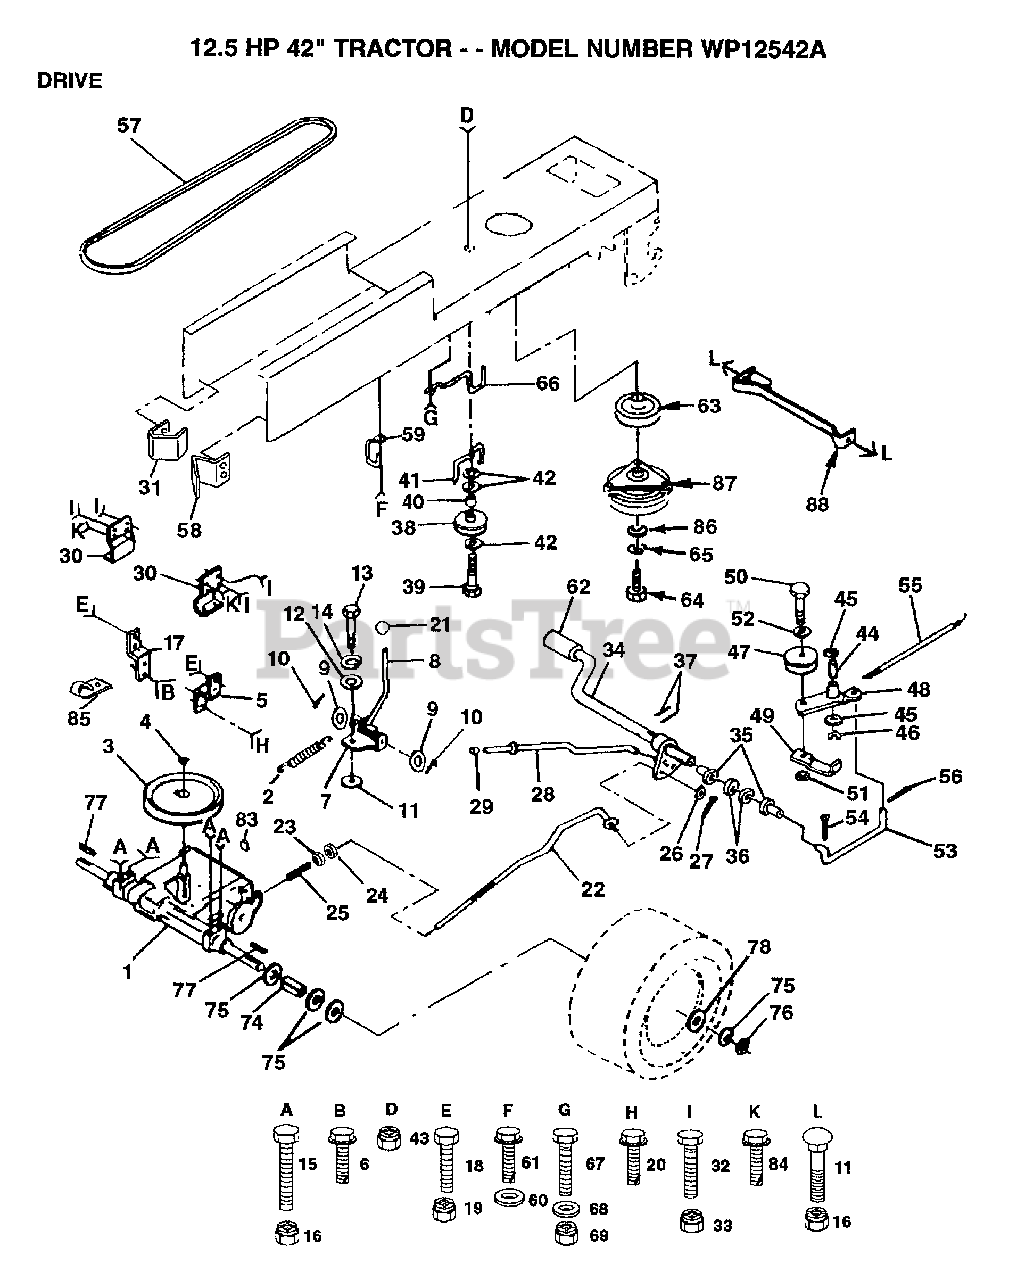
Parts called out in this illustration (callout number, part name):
3	PULLEY TRANS
5	STRAP TORQUE
6	SCREW
8	SHIFT ROD
9	WASHER
10	PIN COTTER 1/8
11	WASH-SHFT PLT LT
12	WASHER LT
14	LOCKWASHER
15	BOLT
17	STRAP TORQUE
20	SCREW
21	KNOB T (1/2-HOLE)
22	BRAKE ROD
23	NUT
24	NUT
25	SPRING ROD LT
26	WASHER
27	COTTER PIN
28	BRAKE PARK ROD
29	PLUNGER CAP T
30	TRANSAXLE MTG BKT
31	"KEEPER,BELT LH T"
32	BOLT
35	NYLON BEARING
36	WASHER LT
38	PULLEY.IDLER.FLAT
39	BOLT
40	SPACER T
41	BELT KEEPER LT
42	WASHER
44	"LY, BEARING"
45	WASHER LT
46	KLIP RING
48	ARM IDLER
49	RETAIN BELT
52	WASHER
53	"LINK, CLUTCH T"
54	COTTER PIN
55	"SPRING, RETURN LT"
56	COTTER PIN
58	"KEEPER,BELT RH T"
60	WASHER
61	SCREW
62	PEDAL COVER T
65	LOCKWASHER
66	KEEPER.BELT.ENG.L
67	BOLT
68	WASHER
74	SPACER LT
75	WASHER
76	E-RING LT
77	SQUARE KEY
78	WASHER
84	SCREW
85	CLIP T
86	WASHER
89	BOLT
